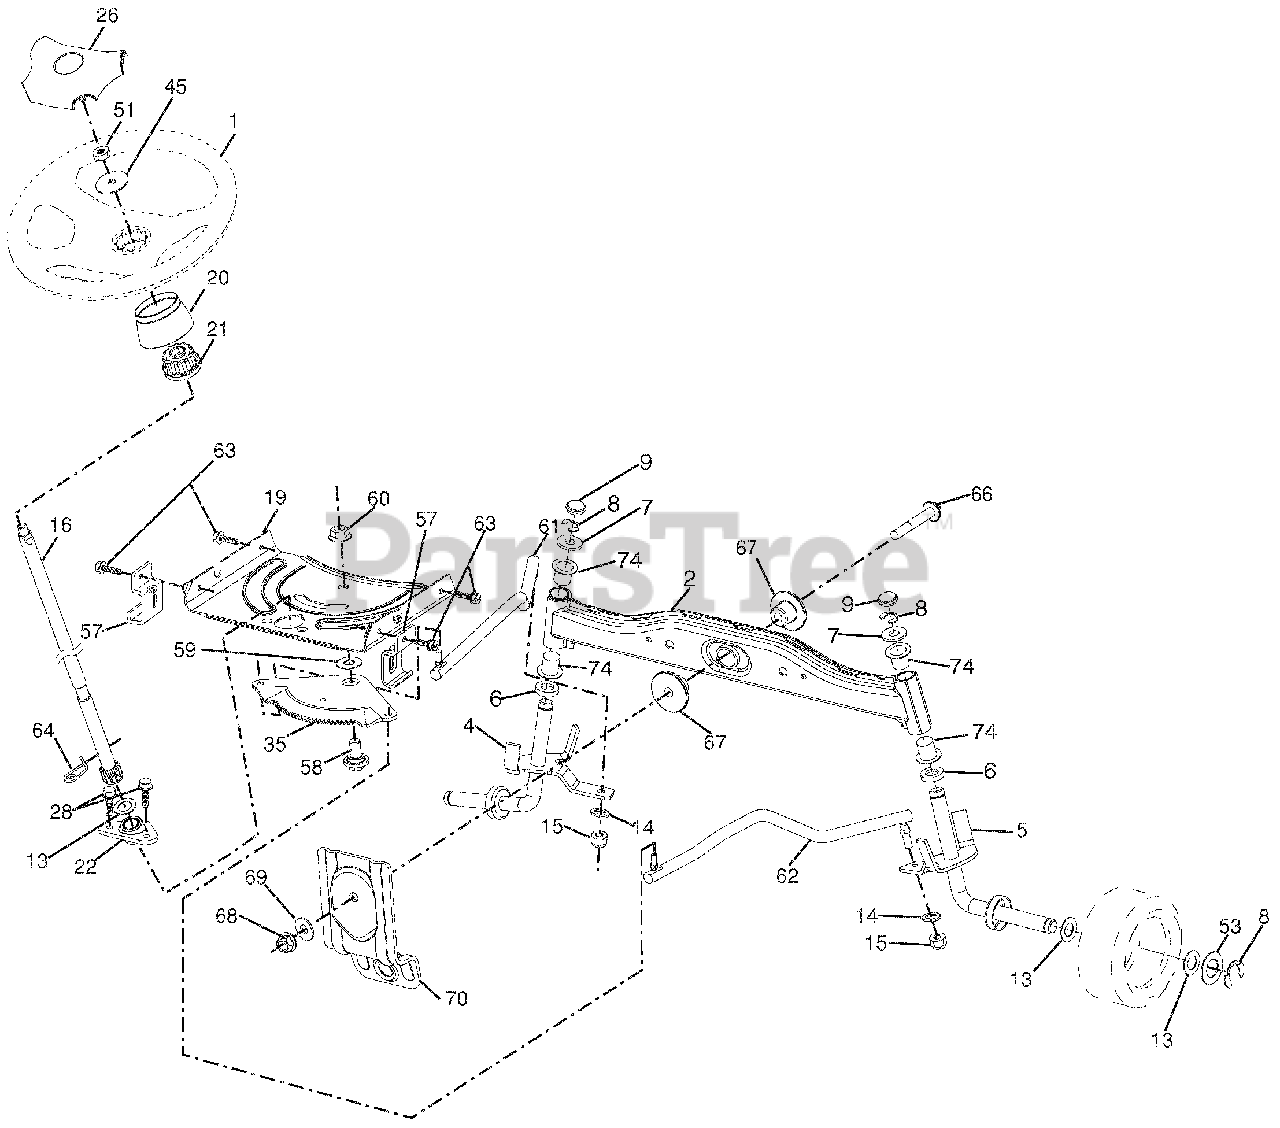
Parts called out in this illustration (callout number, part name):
1	WHEEL.STEERING.HARD RIM.BLACK
2	AXLE ASM.WELDED
4	SPINDLE.WELDED.LH.15"TEX
5	SPINDLE.WELDED.RH.15"TEX
6	WASHER.THRUST..75 X 1.230
7	WASHER.25/32 X 1-5/8 X 16GA.
8	RING.KLIP.#T5304-75
9	CAP.SPINDLE.FR.TOP.BLK.
13	WASHER.25/32 X 1 1/4 X 16 GA.
14	Washer, Lock 3/8
15	NUT.CROWNLOCK.3/8-24
16	SHAFT.STEER.3/4 TEX.NON-PLATED
19	PLATE.STEER.DDL.NLT/NGT
20	BOOT.STEERING.LT.TEX P/L.428
21	ADAPTER.WHEEL.STRG..760
22	BUSHING ASM STEERING.ALUM.NLT
26	CAP.WHL.STRG.HRS/SRS.BLACK
28	SCREW.HEXWSH THDR3/8-16X3/4.BL
35	GEAR SECTOR.PLATE.DDL.NLT/NGT
45	WASHER.9/16ID X 2-3/8OD.12GZIN
51	NUT.HEX.JAM.TOPLOCK.1/2-20 UNF
53	WASHER.HARDEN..793 X 1.637X060
57	BRACKET.UPSTOP.TEX
58	BOLT.SHOULDER.SECTOR.PIVOT.CFM
59	WASHER.THRUST.SECTOR.STEER.NLT
60	NUT.FLANGE LOCK.5/8-11
61	DRAGLINK.LH.BALLSTUD.DDL.
62	DRAGLINK.RH.BALLSTUD.DDL
63	SCREW.5/16-18X3/4.SMGML.TAP/BL
64	RETAINER.CLIP.SPRING.STEERING
66	BOLT.HEX.FGHD.7/16-14 X 3.SERR
67	BUSHING.PM.FRONT AXLE
68	NUT.LOCK.FLANGE.7/16-14.GR5
69	WASHER.1.5 X .505 X .118
70	BRACKET.DECK.SUSPENSION.FRONT
74	BEARING.COL.STRG.BLK.
